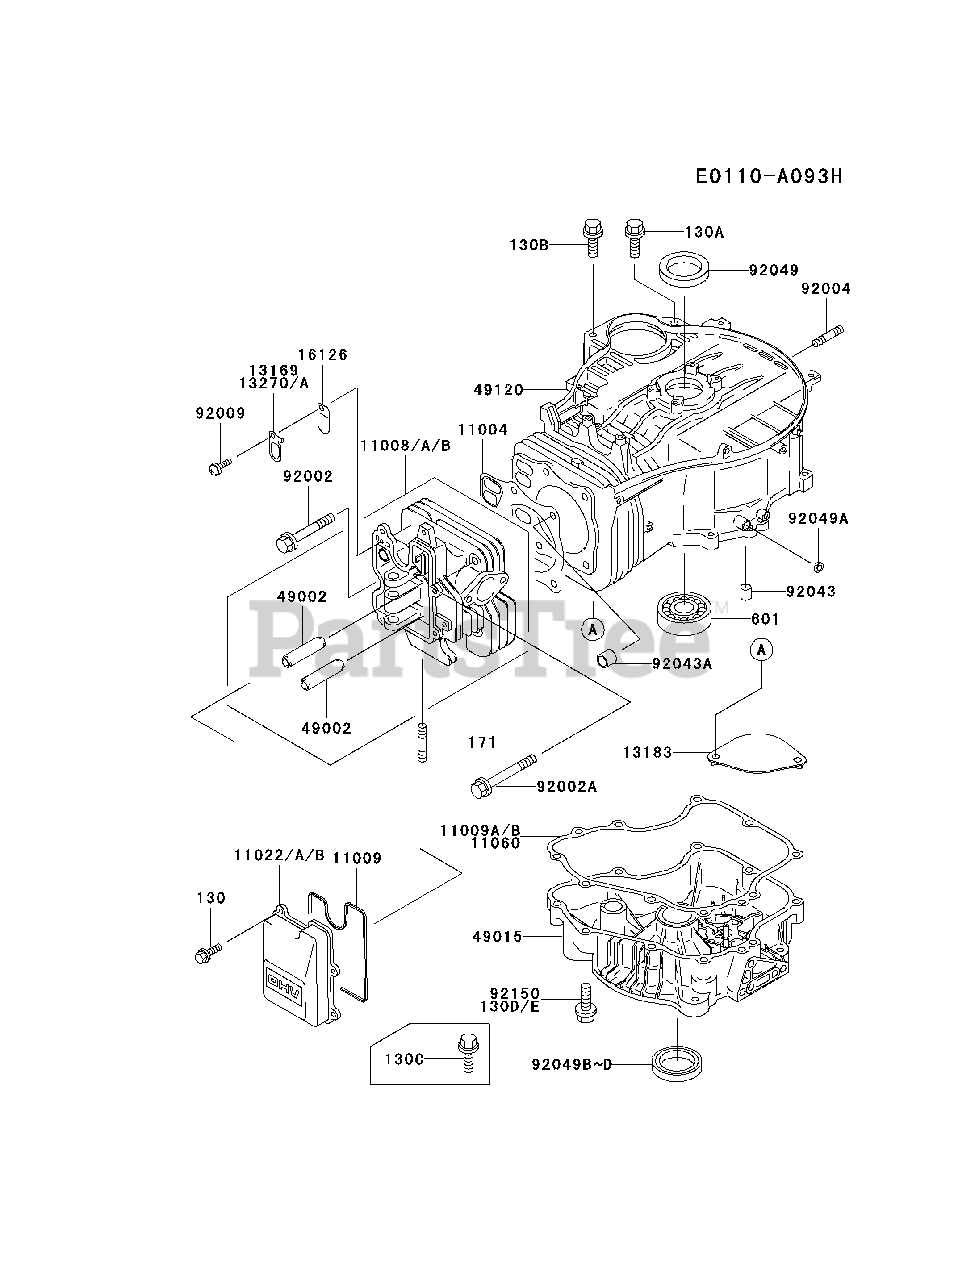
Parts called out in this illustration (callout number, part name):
130A	BOLT-FLANGED
130B	BOLT-FLANGED
130C	BOLT-FLANGED
130E	BOLT-FLANGED
171	BOLT-STUD
601	BEARING,BALL
